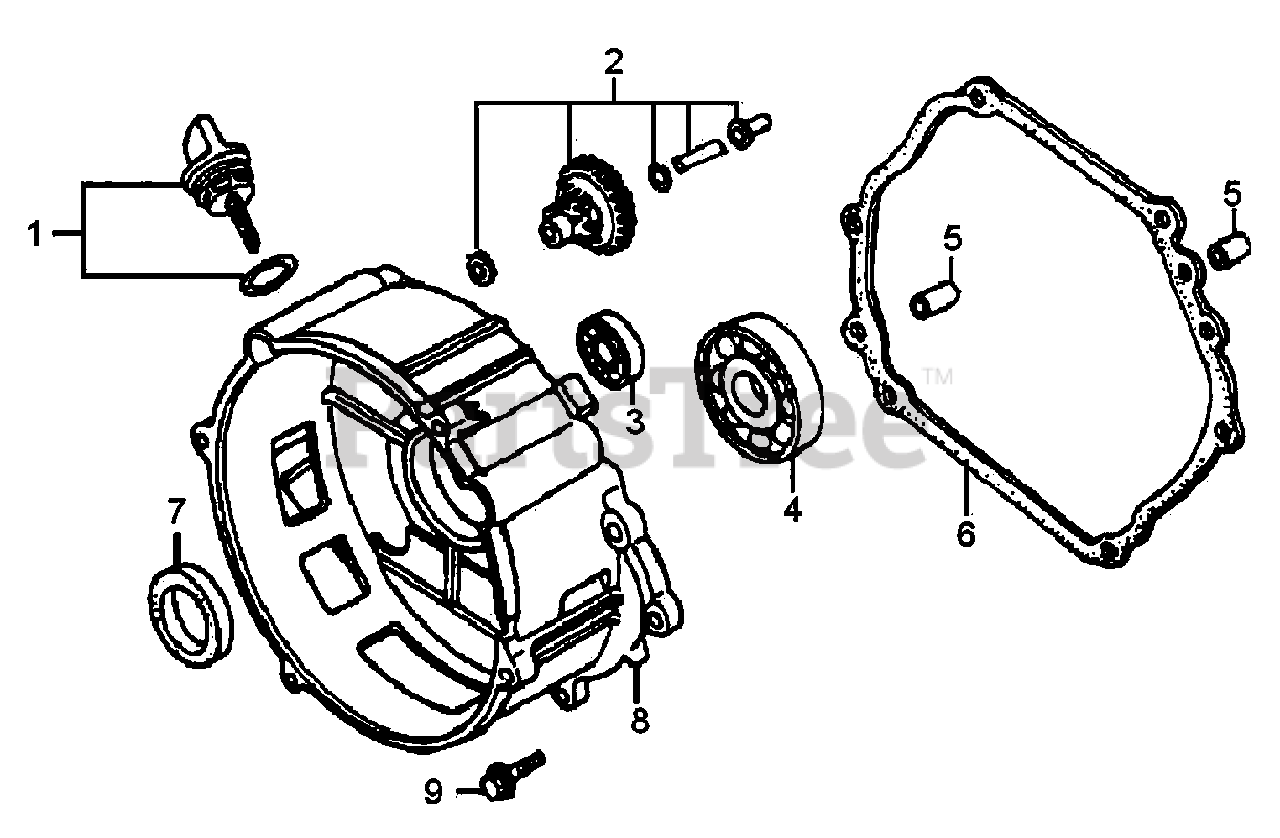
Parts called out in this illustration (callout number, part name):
1	DIPSTICK/CAP ASSY
2	GOVERNOR ASSY.
3	BEARING, RADIAL BALL 6202
4	BEARING, RADIAL BALL 6207
5	PIN, DOWEL 8X12
6	GASKET, CRANKCASE COVER
7	SEAL, OIL
8	CRANKCASE COVER
9	BOLT, FLANGE 8X40
